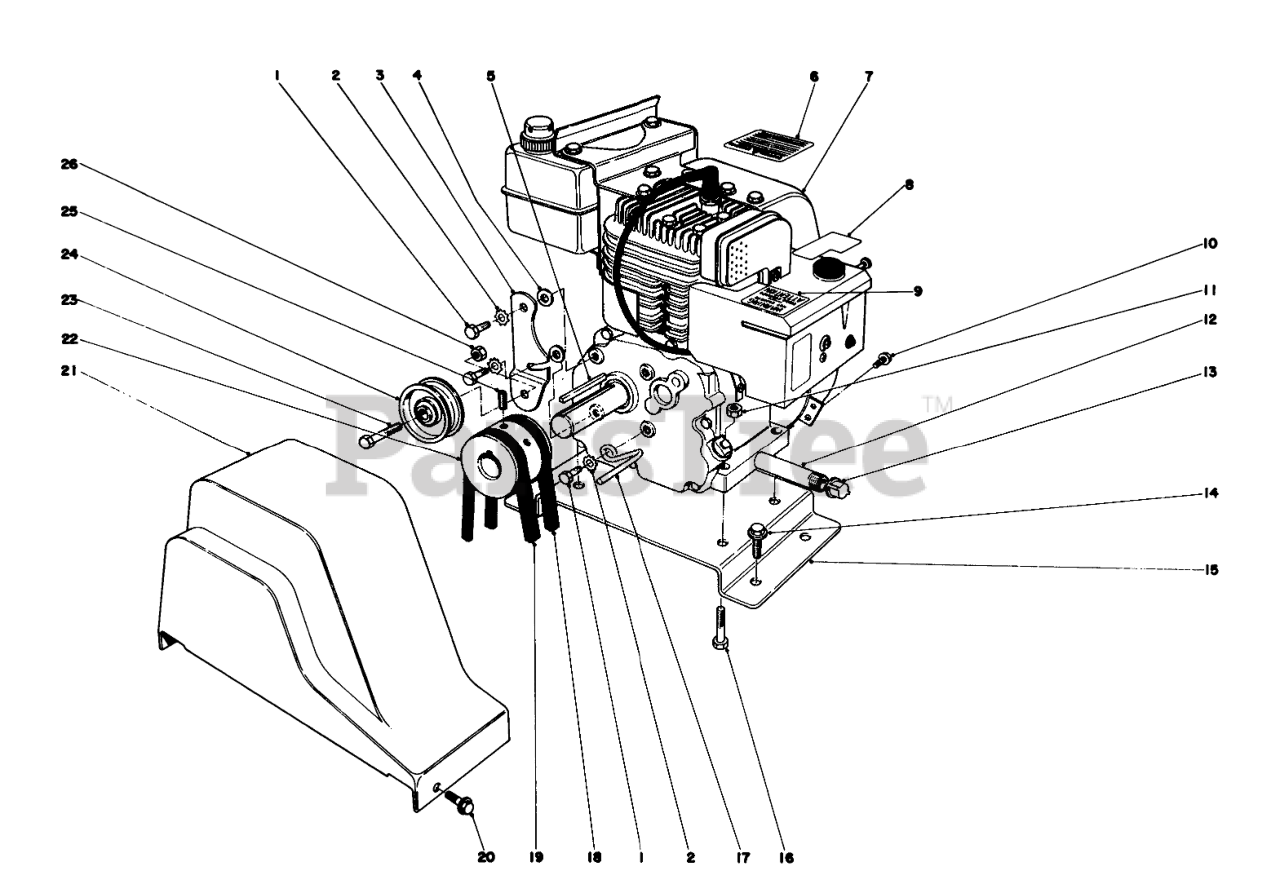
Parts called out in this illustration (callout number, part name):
1	SCREW-HH
2	WASHER-LOCK
3	ENGINE IDLER ARM
4	WASHER-PLAIN
6	CAUTION DECAL
7	Engine
8	CHOKE & PRIMER DECAL
9	Decal Hot Surface Warning
10	SCREW
11	NUT-LOCK, NI
12	NIPPLE-PIPE
13	CAP-PIPE
14	SCREW-HHFTF
15	ENG MTG PLATE R
16	SCREW-HH
17	BELT RETAINER
18	V-BELT
19	V-BELT
20	SCREW-HWH
21	BELT GUARD
22	ENGINE PULLEY
23	SCREW-HH
24	PULLEY-IDLER
25	Screw-Set
26	NUT-HEX
